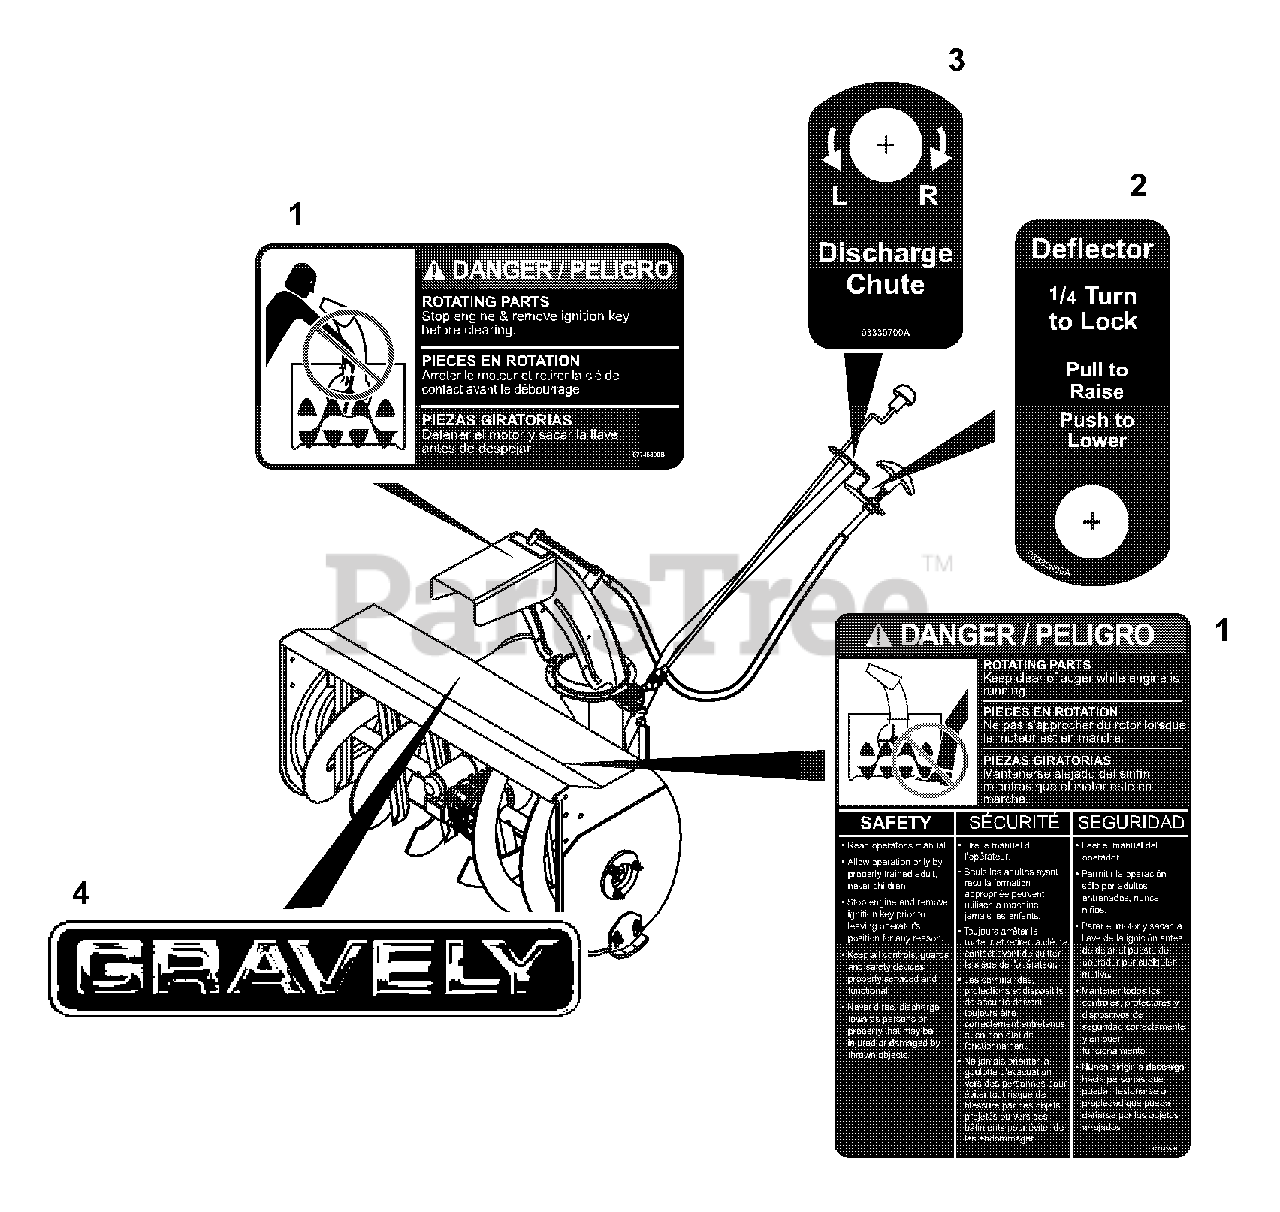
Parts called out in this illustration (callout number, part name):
1	Decal Set, Sno-Head
2	Decal Deflector
3	Decal-Chute
4	Decal- 15" Gravely Logo
